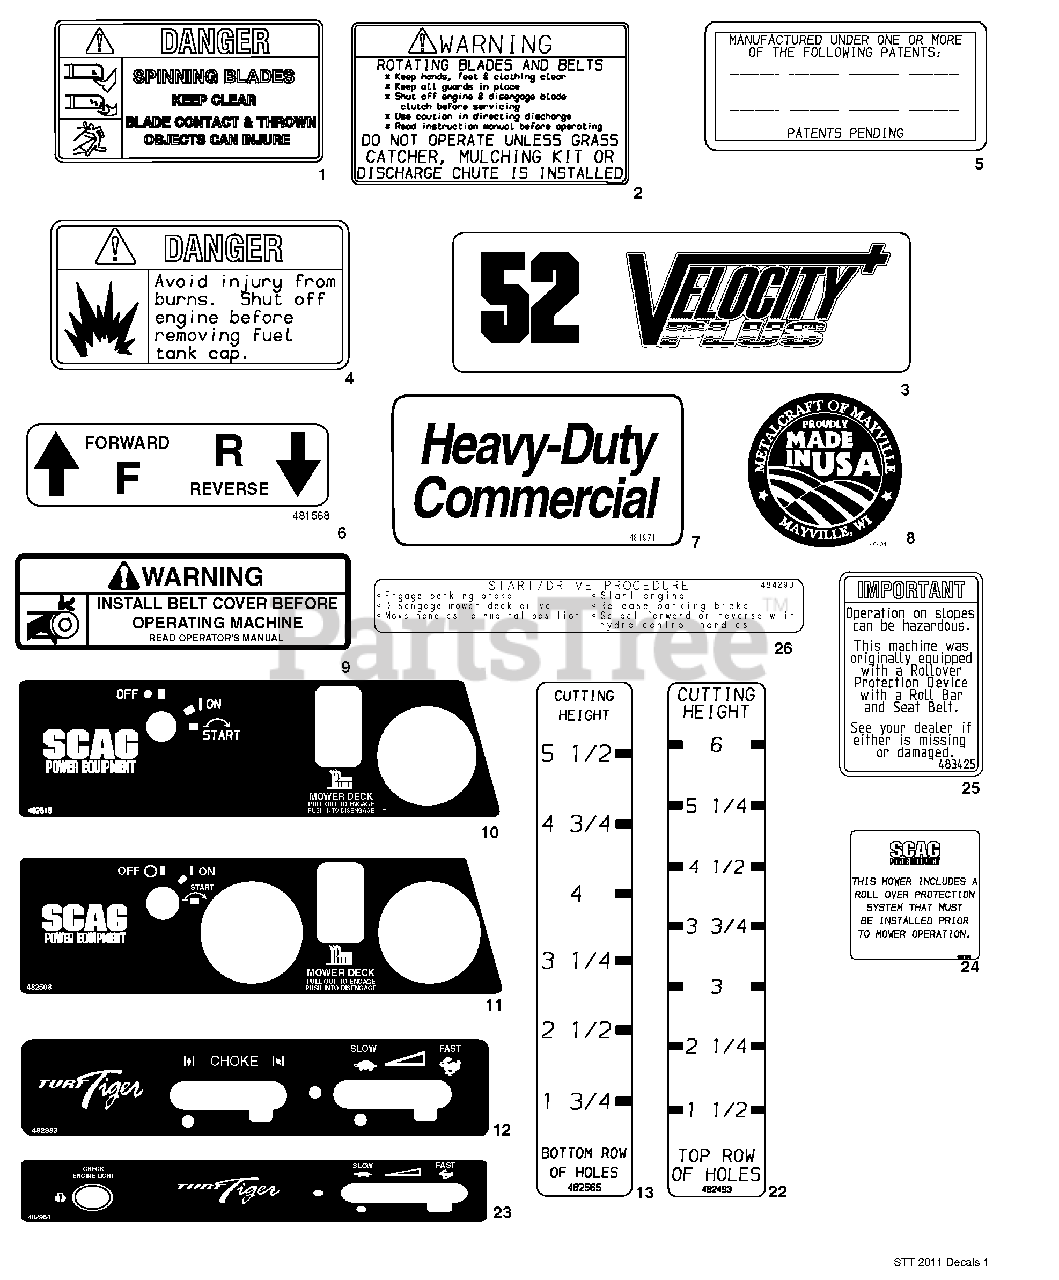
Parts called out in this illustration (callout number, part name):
1	Decal, Danger - Spinning Blades
2	Decal, Warning - Rotating Blades
3	Decal, 52 Velocity Plus
3	Decal, 61 Velocity Plus
3	Decal, 72 Advantage
3	Decal, 72 Velocity Plus
4	Decal, Fuel Tank
5	Decal, Patents
6	Decal, Traction Control
7	Decal, Heavy-Duty Commercial
8	Decal, Metalcraft-Made In USA
9	Decal, Belt Cover
10	Decal, Instrument Panel - Upper
11	Decal, Instrument Panel - Upper
12	Decal, Instrument Panel-Lower
13	Decal, Cutting Height - Lower
22	Decal, Cutting Height - Upper
23	Decal, Instrument Panel - Lower
24	Decal, ROPS
25	Decal, ROPS
26	Decal, Start / Drive
